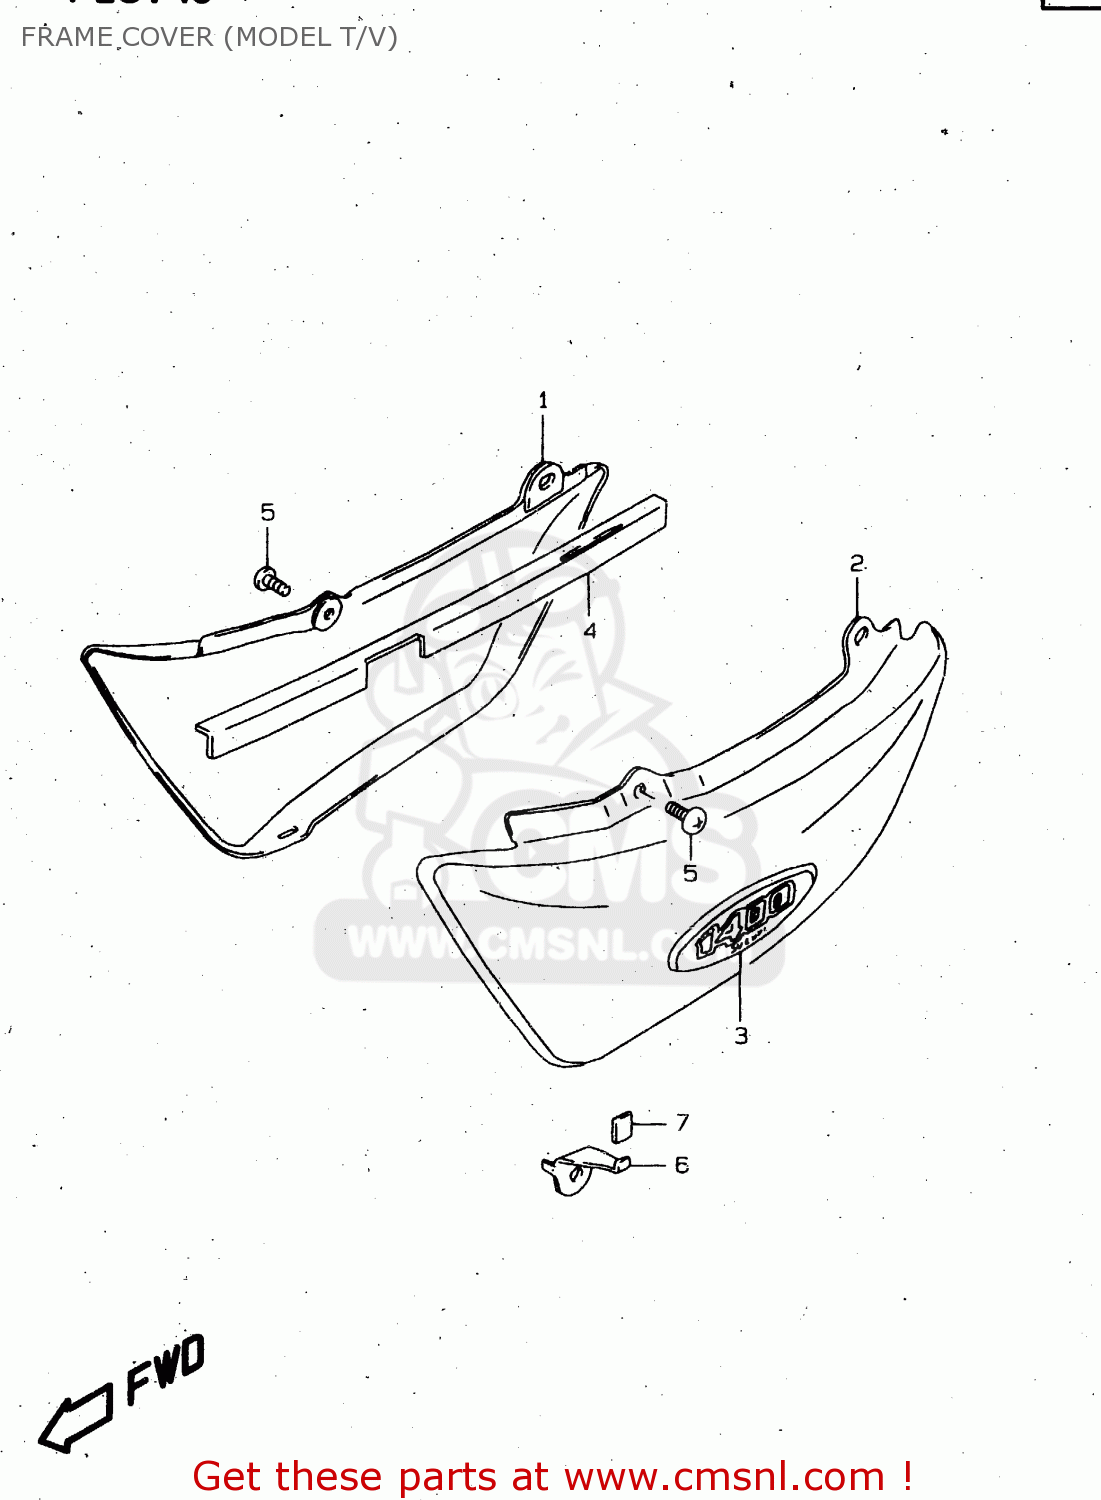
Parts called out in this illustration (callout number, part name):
1	1
2	COVER,FRAME,L
3	EMBLEM,FRAME COVER
4	PROTECTOR,FRAME COVER,R
5	SCREW 6X12
6	HOOK,FRAME COVER,L
7	CUSHION,FRAME COVER HOOK
